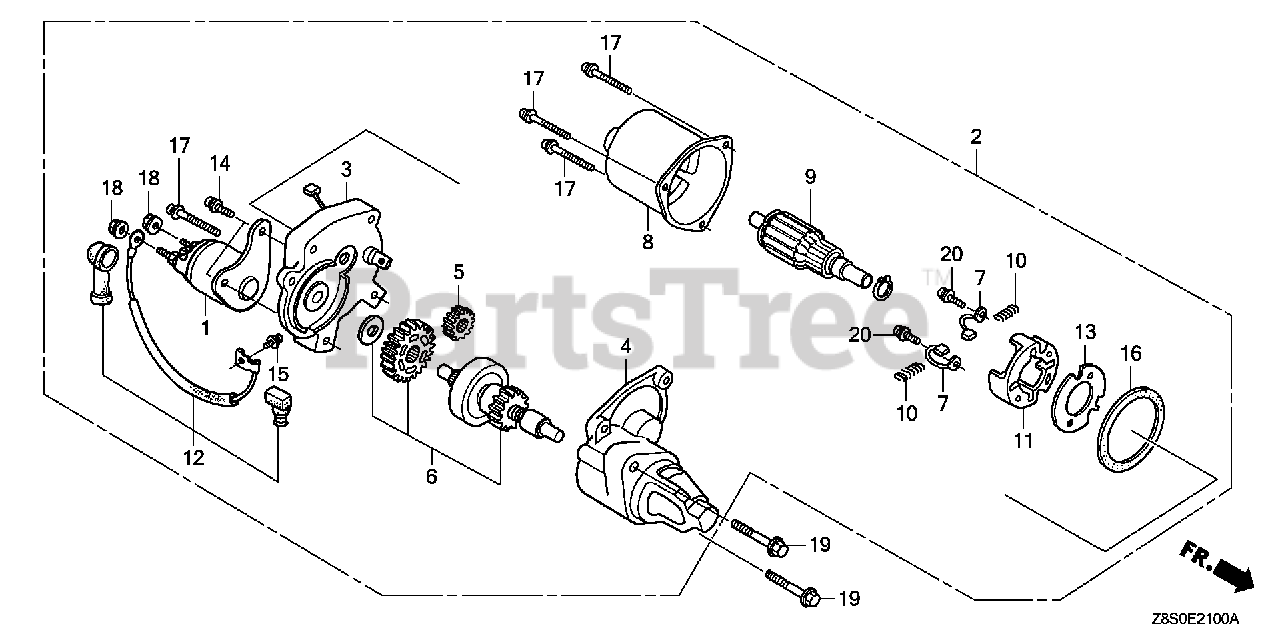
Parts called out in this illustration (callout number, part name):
1	CONTACTOR ASSY.
2	STARTER MOTOR UNIT
3	BRACKET, CENTER
4	BRACKET, FR.
5	GEAR, DRIVE PINION
6	CLUTCH, OVERRUNNING
10	SPRING, BRUSH RETURN
11	HOLDER, BRUSH
12	WIRE, WATER COVER
14	BOLT-WASHER (5X14)
15	SCREW-WASHER (4X6)
17	SCREW-WASHER (5X32)
18	NUT-WASHER (6MM)
19	BOLT, FLANGE (8X40)
20	SCREW-WASHER (4X14)
